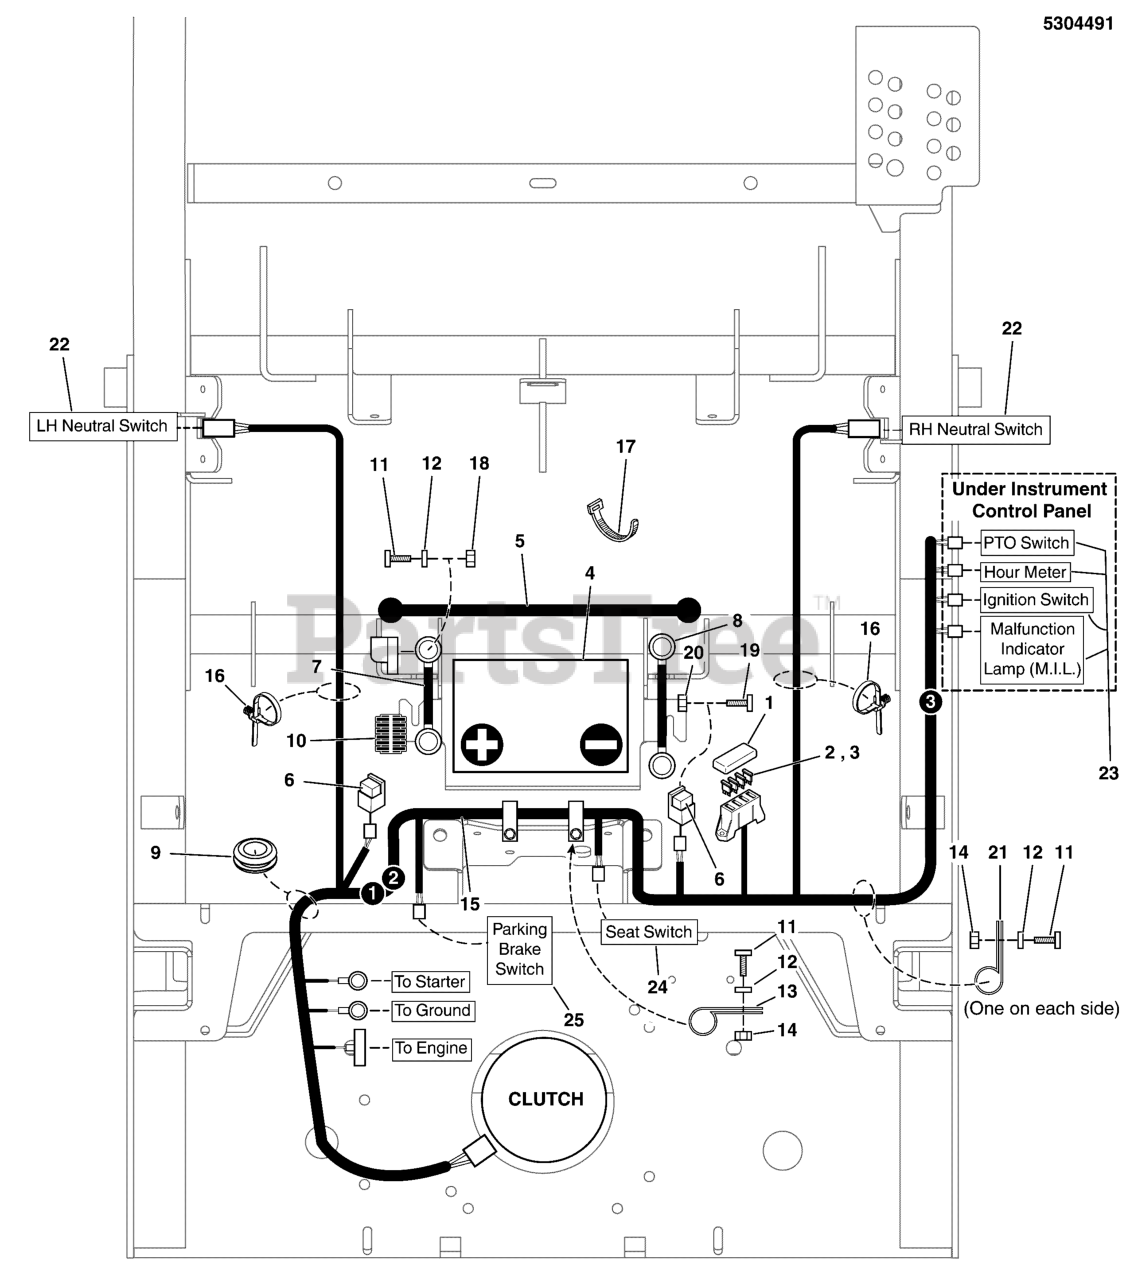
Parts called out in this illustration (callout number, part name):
1	COVER, VINYL, FUSE BLOCK
2	FUSE, ATO-15 (15 AMP)(SV)
3	FUSE, ATO-20 (20 AMP)(SV)
4	BATTERY, 11U1L, 350 CCA
5	STRAP, BATTERY, 14 LONG, Rubber
6	RELAY, 12 VOLT, 40 AMP
7	BATTERY CABLE, POS, 22, 1/4-5/16
8	BATTERY CABLE, NEG, 22, 1/4-5/16
9	GROMMET, 2" ID
10	WIRE LOOM, 3/8 ID X 17 IN
11	BOLT, 1/4"-20 X 3/4" GD5 YZ
12	WASHER, 1/4 SAE
13	CLAMP, VINYL INSULATED, 1.00
14	NUT, 1/4-20 Hex Nylock Flange
15	WIRE HARNESS, 37HP BRIGGS EFI, F320Z
16	TIE, SELF-LOCKING, 8", PUSH MOUNT
17	TIE, SELF-LOCKING, 12"
18	NUT, 1/4-20 HEX SERR. FLANGE
19	SCREW, #10-24 X 3/4" ROUND PHILLIPS
20	NUT, Hex, Nylon Lock, #10-24
21	CLAMP, VINYL INSULATED, .625
22	SWITCH, PLUNGER, N.O., BOLT-ON
23	Refer to: Instrument Control Panel Group
24	SWITCH, PLUNGER, N.C.
25	SWITCH, DP NO/NC SNAP-IN
